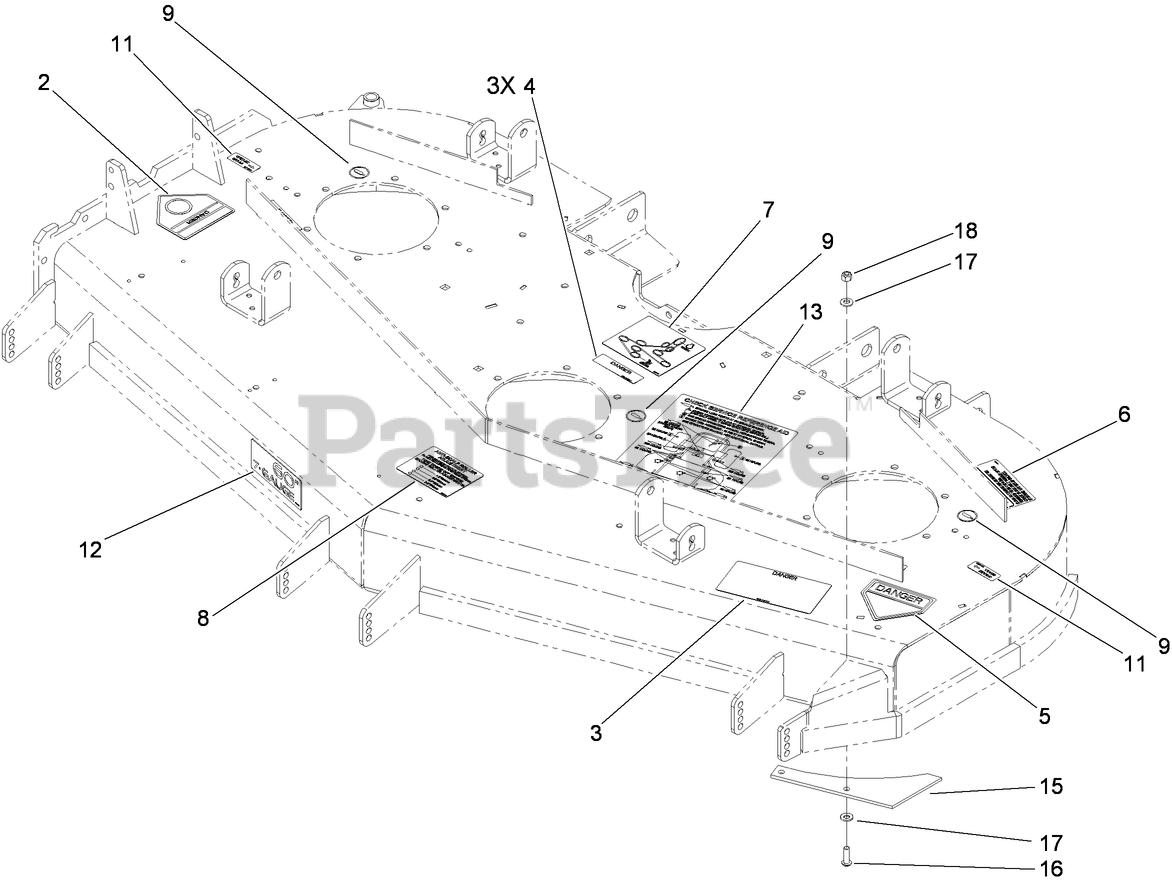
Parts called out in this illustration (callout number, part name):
2	DECAL-DANGER
3	DECAL-DANGER, THROWN OBJECT
4	DECAL-COVER, MISSING
5	DECAL-DANGER
6	DECAL-TORQUE
7	Decal-Routing, Belt
8	DECAL-SCALP, ANTI
9	DECAL-GREASE
11	Decal-Grease
13	DECAL-SERVICE, CHECK
15	PLATE-TURBO
16	SCREW-HSBH
17	WASHER-SPRING
18	NUT-LOCK, NI
